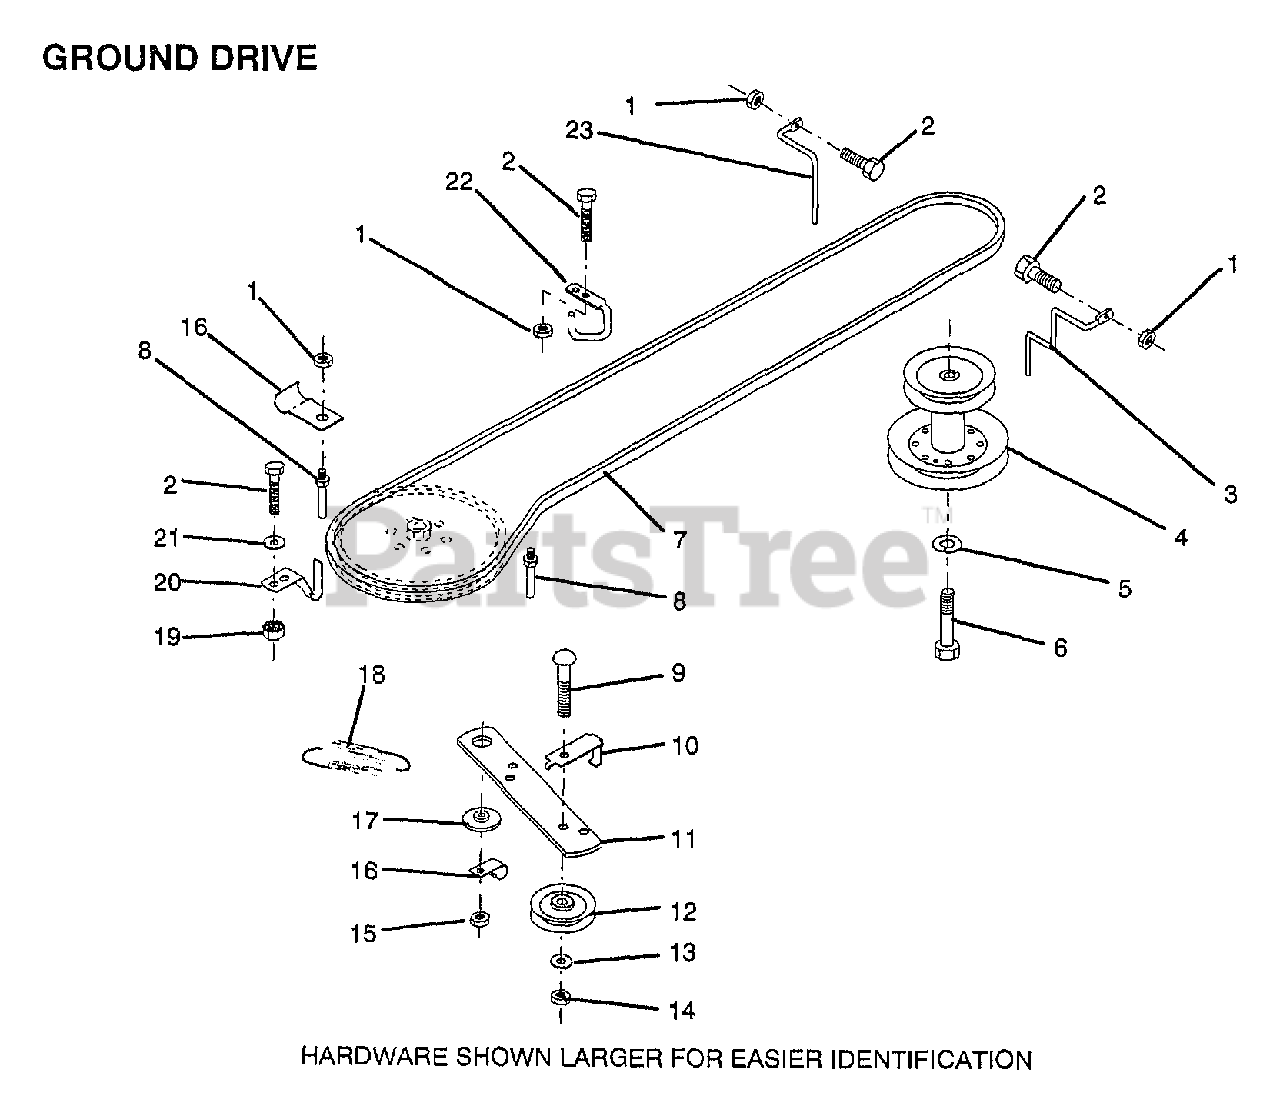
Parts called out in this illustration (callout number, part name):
2	BOLT
3	KEEPER ENG BEL LH
5	LOCKWASHER
6	BOLT
7	BELT
8	"KEEPER,DRIVE BELT"
9	BOLT
10	"KEEP,IDLER DR BEL"
12	PULLEY.IDLER.FLAT
13	WASHER
14	LOCKNUT
16	"CLIP,INSULATOR"
17	SPACER RETAINER
20	"KEEPER,DR BELT "
21	WASHER
22	"KEEPER,FRA DR BEL"
23	KEEPER ENG DR RH
